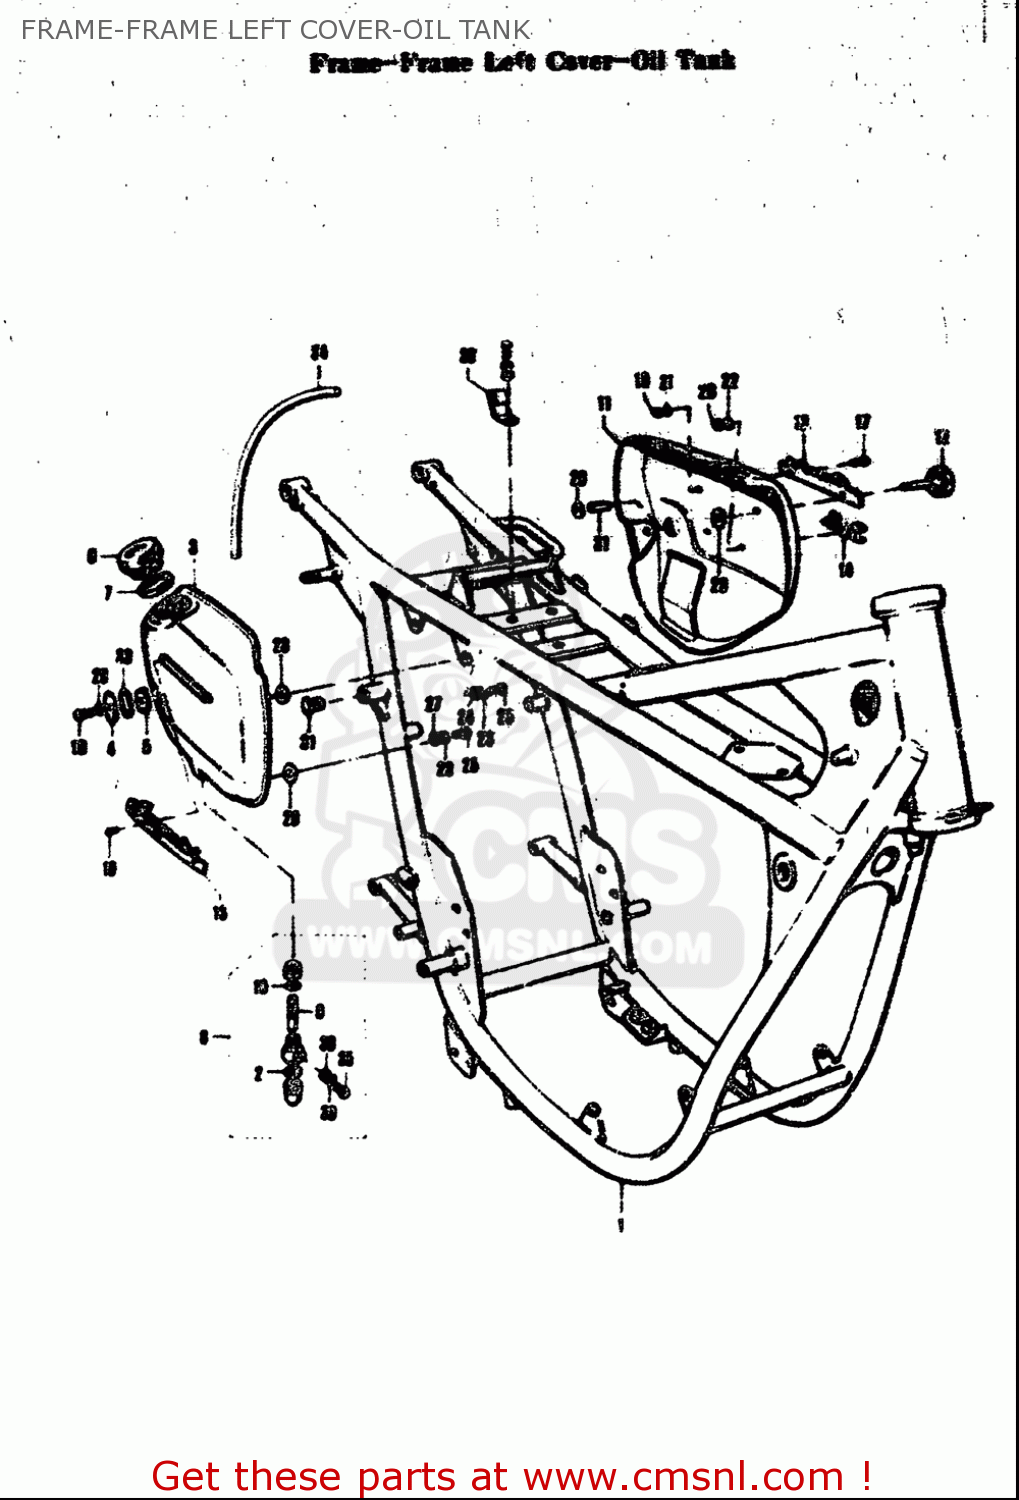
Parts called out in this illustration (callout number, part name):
5	LENS SET,OIL INSPECTION
6	CAP,OIL TANK
7	GASKET,OIL TANK FILLER CAP (NAS)
9	UNIT,OIL FILTER
10	GASKET,OIL OUTLET JOINT (NAS)
16	SCREW
18	SCREW
19	NUT
20	NUT
21	WASHER,LOCK
22	WASHER,LOCK
23	WASHER,LOCK
24	WASHER
25	BOLT(6X14)
26	NUT
27	WASHER(6.5X18X1.6)
29	GASKET(5X9.5X1) (NAS)
30	GASKET(6.2X11X1).2 (NAS)
32	CAP(OD:14)
33	O RING(D:3,ID:23)
35	UNION BOLT
